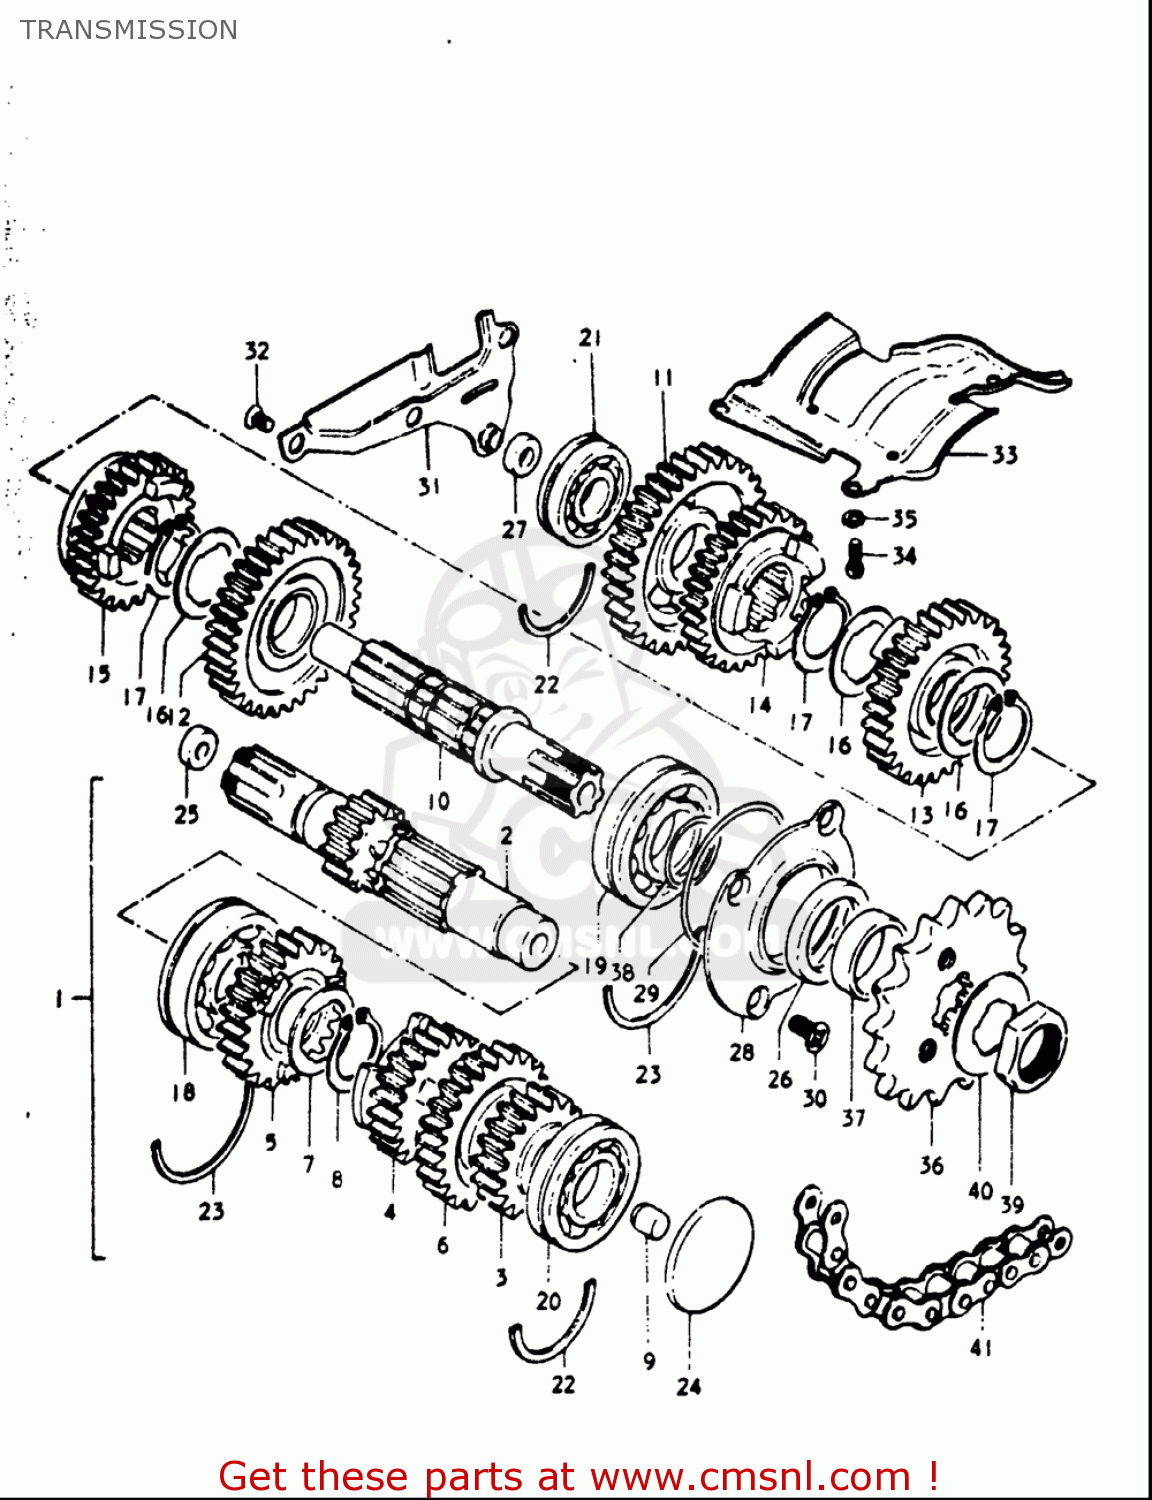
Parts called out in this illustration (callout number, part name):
7	WASHER,LOCK
8	CIRCLIP
9	PLUG
16	WASHER,LOCK
17	CIRCLIP
19	BEARING
20	BEARING(20X47X14)
22	C RING
25	SEAL,OIL (10X17X5)
26	SEAL,OIL(32X42X6)
27	SEAL,OIL(8X14X4)
29	O RING(D:2,ID:64.5)
30	SCREW
32	SCREW
33	GUIDE,TRANSMISSION OIL
34	SCREW
35	WASHER,LOCK
36	SPROCKET,ENGINE
37	SPACER(25X32X10.7)
38	O RING(D:1,ID:24.5)
39	NUT
40	WASHER,LOCK
